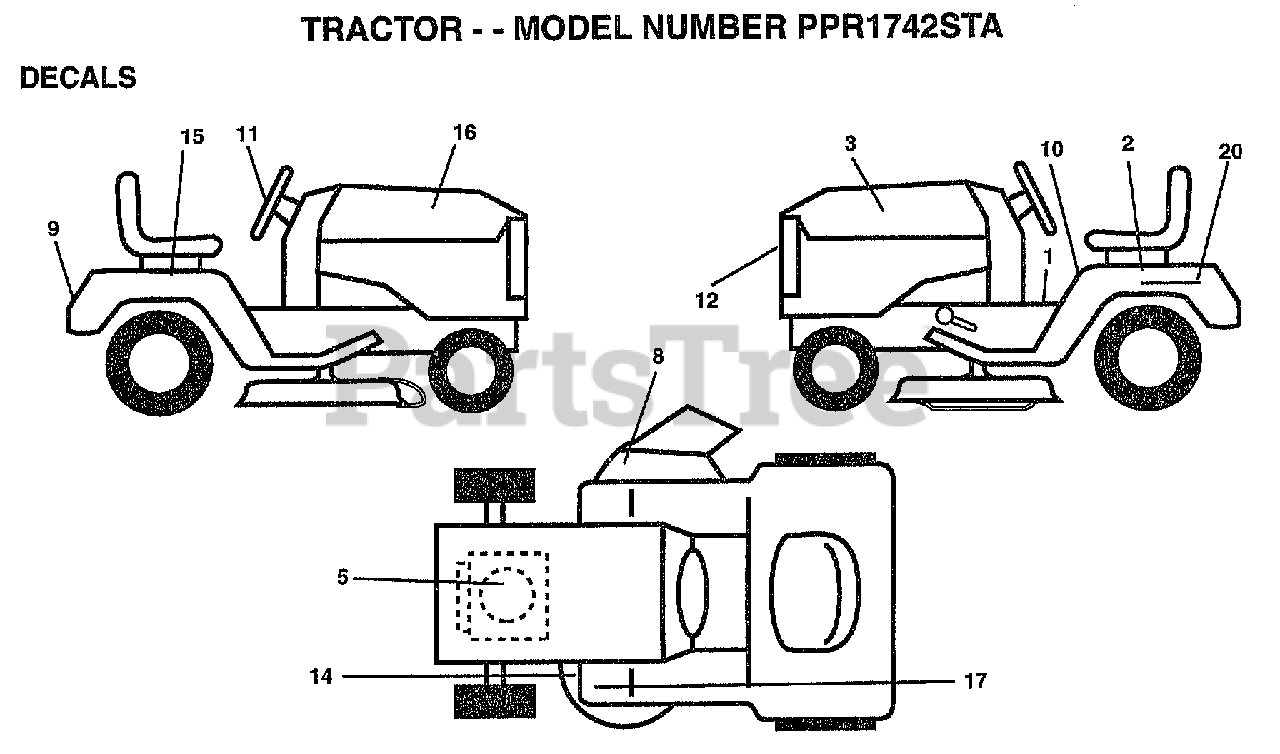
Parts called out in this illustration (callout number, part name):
1	"DECAL.OPER,SDL"
2	DECAL.FENDER.SIDE.LH
3	DECAL.HOOD.LH
5	DECAL.ENGINE.HP.B&S
8	"DECAL, WARNING"
9	DECAL.FENDER.LOGO
10	DECAL.CAUT.ENG/FR
11	DECAL.INS.WHL.STRG
12	DECAL.GRILLE.
14	"DECAL-SCHEM,BELT"
15	DECAL.FENDER.SIDE.RH
16	DECAL.HOOD.RH
17	DECAL T
20	DECAL.BATRY.3-3908
